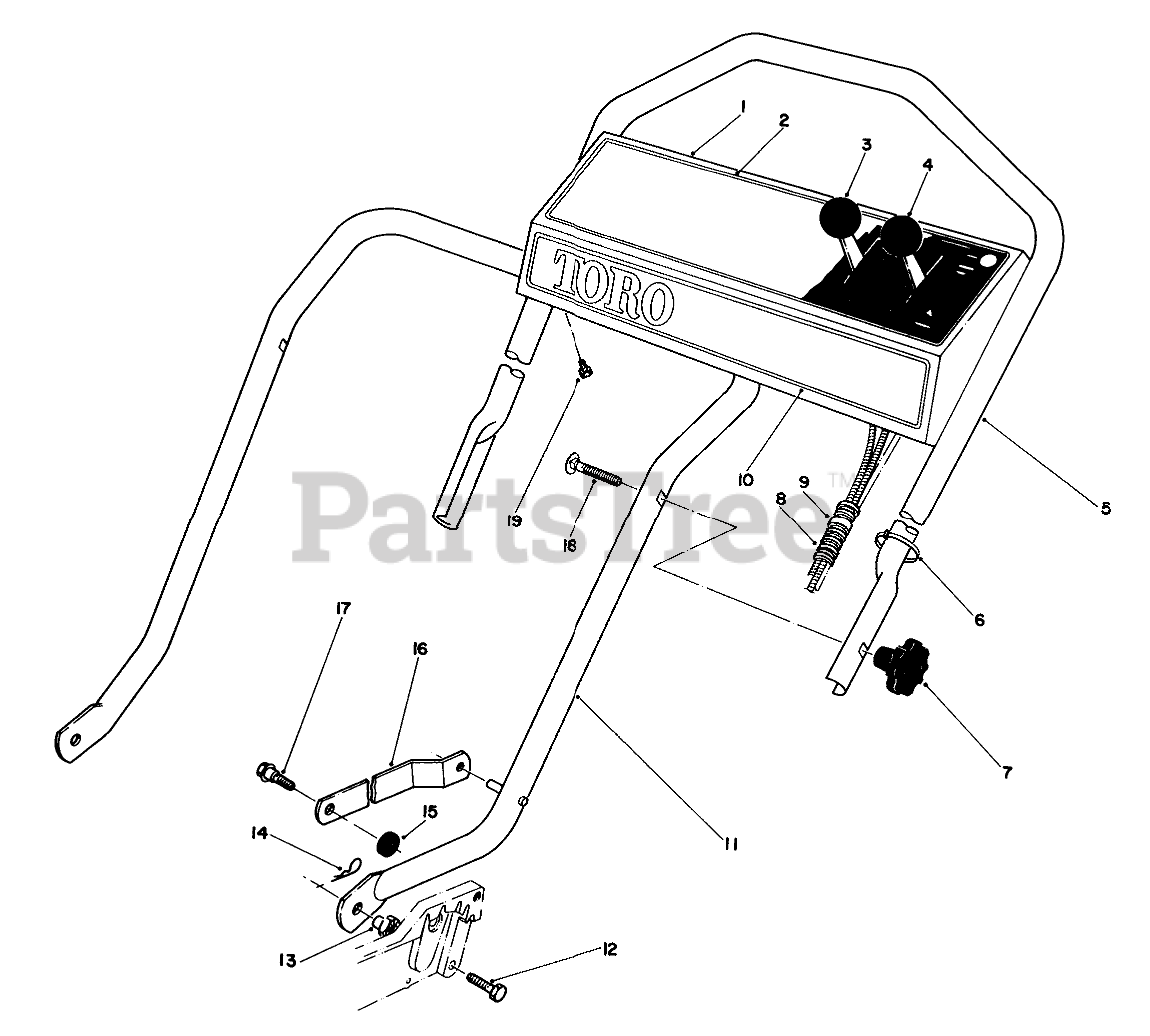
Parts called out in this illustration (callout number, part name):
1	Panel-Control (Incl. Ref. #2)
2	OBS INSTRUCTION DECAL
3	SERVICE TRACT. CONTROL
4	SERVICE THROTTLE CONTRO
5	Handle-Upper
6	TIE-CABLE
8	CONTROL CABLE COVER
9	FITTING-RING
10	Decal-Toro
11	LOWER HANDLE ASM
12	SCREW-HH
13	HANDLE PIVOT NUT
14	PIN-COTTER, HAIR
15	SPACER
16	HANDLE LATCH
17	SCREW-SHOULDER
18	5/16-18 X 2 HNDLE SCREW
19	SCREW-HWHTF
